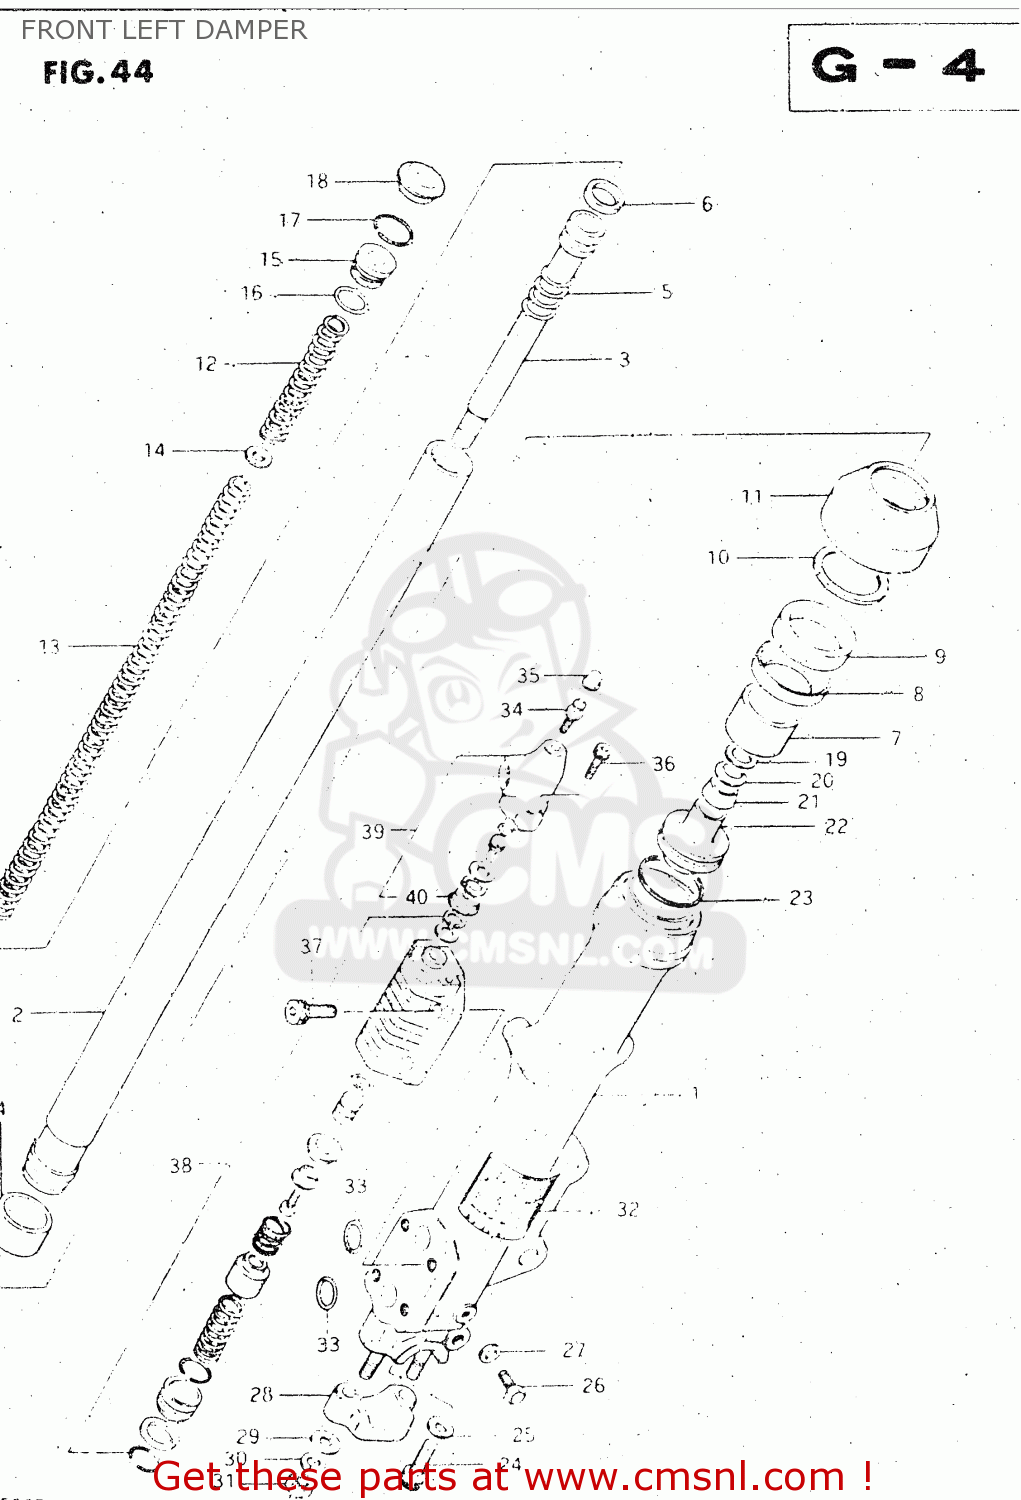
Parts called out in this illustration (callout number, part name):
1	OUTER TUBE LH
2	INNER TUBE
3	CYLINDER
4	PISTON
5	SPRING,FORK REBOUND
6	RING
7	BUSH,GUIDE
8	SPACER,SEAL
9	OIL SEAL,FRONT FORK
10	CIRCLIP,FORK OIL SEAL
11	BOOT
12	SPRING (A)
13	SPRING (B)
14	WASHER,SPRING
15	SPRING SEAT B
16	O-RING
17	RING,STOPPER
18	CAP
19	VALVE
20	SPRING,VALVE
21	VALVE,OIL LOCK PIEACE
22	PIECE,FRONT FORK OIL LOCK
23	PISTON RING,FRONT FORK
24	BOLT(8X27)
25	GASKET (NAS)
26	BOLT
27	GASKET,DRAIN,PLUG (NAS)
28	HOLDER,AXLE
29	WASHER
30	LOCK WASHER
31	NUT
32	LABEL
33	O RING,FR FORK
34	BREATHER
35	CAP
36	BOLT
37	BOLT
38	MODULATOR VALVE SET
39	MODULATOR PLANGER SET
40	SEPARATOR,FRONT FORK MODULATOR
